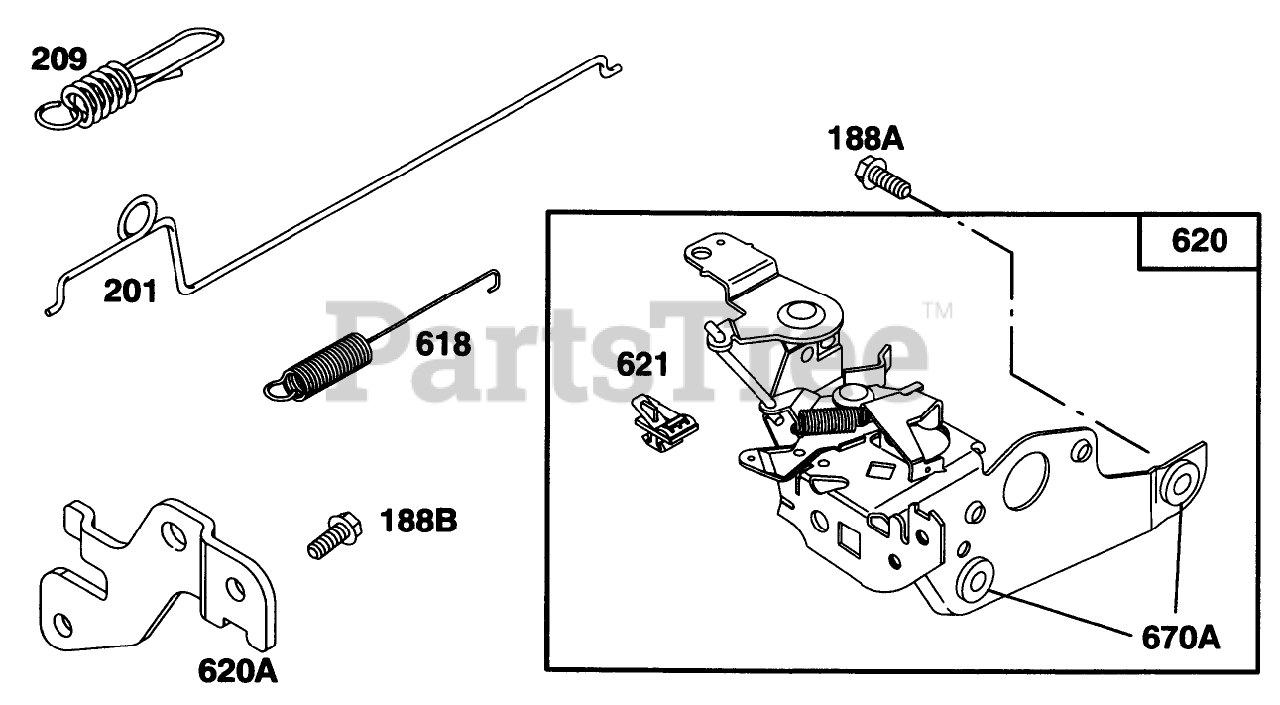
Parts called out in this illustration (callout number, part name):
188A	Screw-Hex.
188B	Screw-Hex.
201	Link-Govemor
209	Spring-Govemor
618	Spring-Choke
620	Bracket-Carburetor
621	Switch
670A	Spacer
